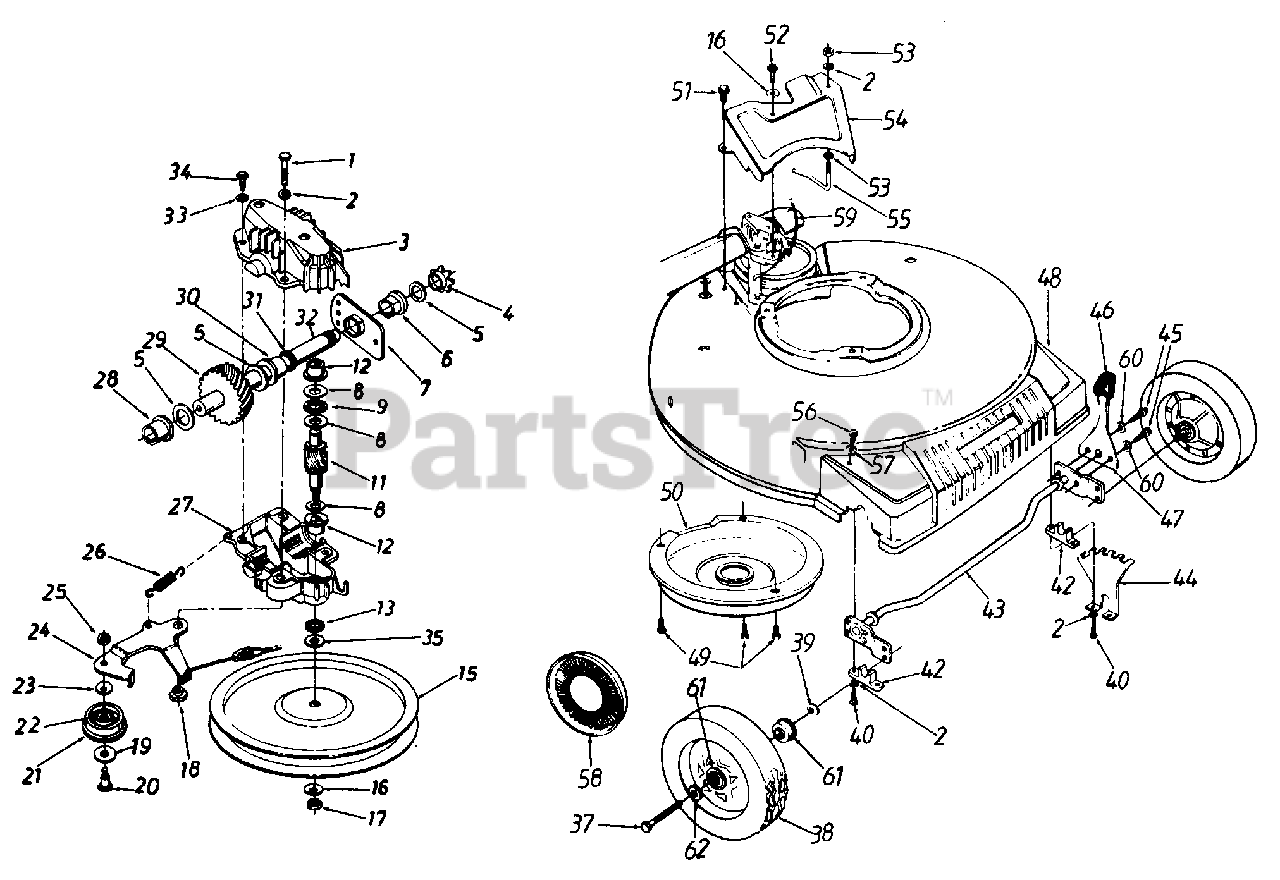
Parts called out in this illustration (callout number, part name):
1	SCREW-HEX
2	LOCK WASHER 1/4 DIA
3	HOUSING HALF-UPPER
4	SPROCKET-7T
5	WASHER-FL
6	BEARING-HEX FLANGE
8	WASHER-THRUST.382 X .684
9	BEARING-THRUST
11	SHAFT-PINION 11 T
12	BEARING-FLANGE
13	SEAL-OIL-.375 ID
16	WASHER-SPRING BELL
17	NUT-LH THD-1/4 X 28
18	SPACER-SHLD
19	WASHER-FL .995 X .032
20	SCREW-SHLD
21	PULLEY
22	BEARING-NEEDLE
23	BELL-WASH
24	BRACKET ASSY-IDLER
25	NUT-HEX 1/4-28
26	SPRING-EXTENSION
27	HOUSING HALF-LOWER
28	BEARING-FLANGE
29	SHAFT-ASSY W/GEAR
30	BEARING-FLANGE
32	SHAFT-ASSY W/GEAR
33	WASHER-LOCK-#10
34	SCREW-HEX WASH HD TAP
35	WASHER-HEX
37	SCREW-SHLD .498 DIA X 1.450
38	WHEEL ASSY W/TIRE
39	WASHER-BELL .400 ID X .88 X .060
40	SCREW-HEX WASH SF TAPP
42	BUSHING-BLOCK
43	AXLE ASSY-FR
44	BRACKET-HGT-ADJ
45	SCREW-TAP 1/4-20 X .38
46	KNOB
47	LEVER-SPRING
48	FRONT END-PLASTIC
49	SCREW-HEX B-TAP 1/4 X .38
50	COVER-BELT
51	SCREW-HEX WASH SF TAPP
52	SCREW-HEX B-TAP 1/4-.62
53	NUT-HEX 1/4-20
56	SCREW-AB TAP
57	WASHER-BELL .337 X .867 X .057
58	HUB CAP
59	CABLE-CLUTCH CONTROL
60	WASHER-EXTERN L 1/4
61	BEARING-BALL
62	WASHER-WAVE .530 X .780 X .013
